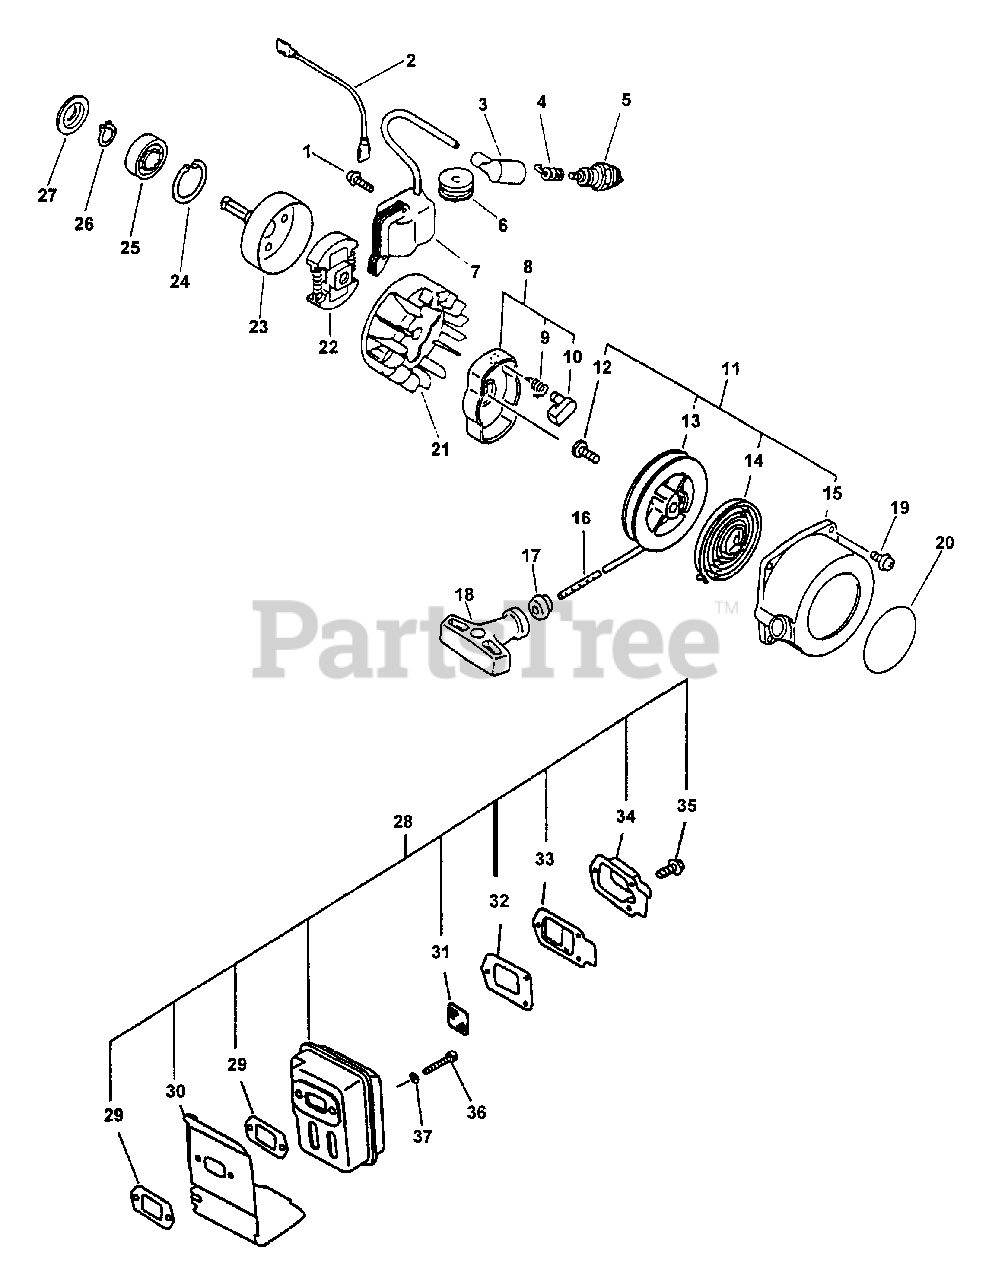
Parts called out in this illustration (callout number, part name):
1	SCREW - 4X22
2	LEAD - GROUND
3	CAP, SPARK PLUG
4	TERMINAL, SPARK PLUG CAP
5	SPARK PLUG -- BPM-7Y
6	GROMMET
7	COIL, IGNITION
8	STARTER PAWL ASSY
9	SPRING, RETURN
10	PAWL, STARTER - BLACK
11	STARTER ASSY
13	REEL, ROPE
14	SPRING, REWIND
15	CASE, STARTER
16	ROPE, STARTER - 3X1000
17	GUIDE, ROPE
18	GRIP, STARTER
19	SCREW - 4X16
20	LABEL - BRAND
21	FLYWHEEL
22	CLUTCH ASSY
23	DRUM, CLUTCH
24	RING, RETAINING - 32
25	BEARING, BALL - 6201
26	RING, RETAINING - 12
27	RETAINER, PIPE
28	MUFFLER ASSY
29	GASKET, EXHAUST
30	COVER, MUFFLER
31	SCREEN, SPARK ARRESTOR
32	GASKET, EXHAUST
33	GASKET, EXHAUST - INNER
34	GUIDE, EXHAUST
34	GUIDE, EXHAUST - OUTER
35	SCREW - 4X10
36	SCREW - 5X55
37	WASHER - 5
